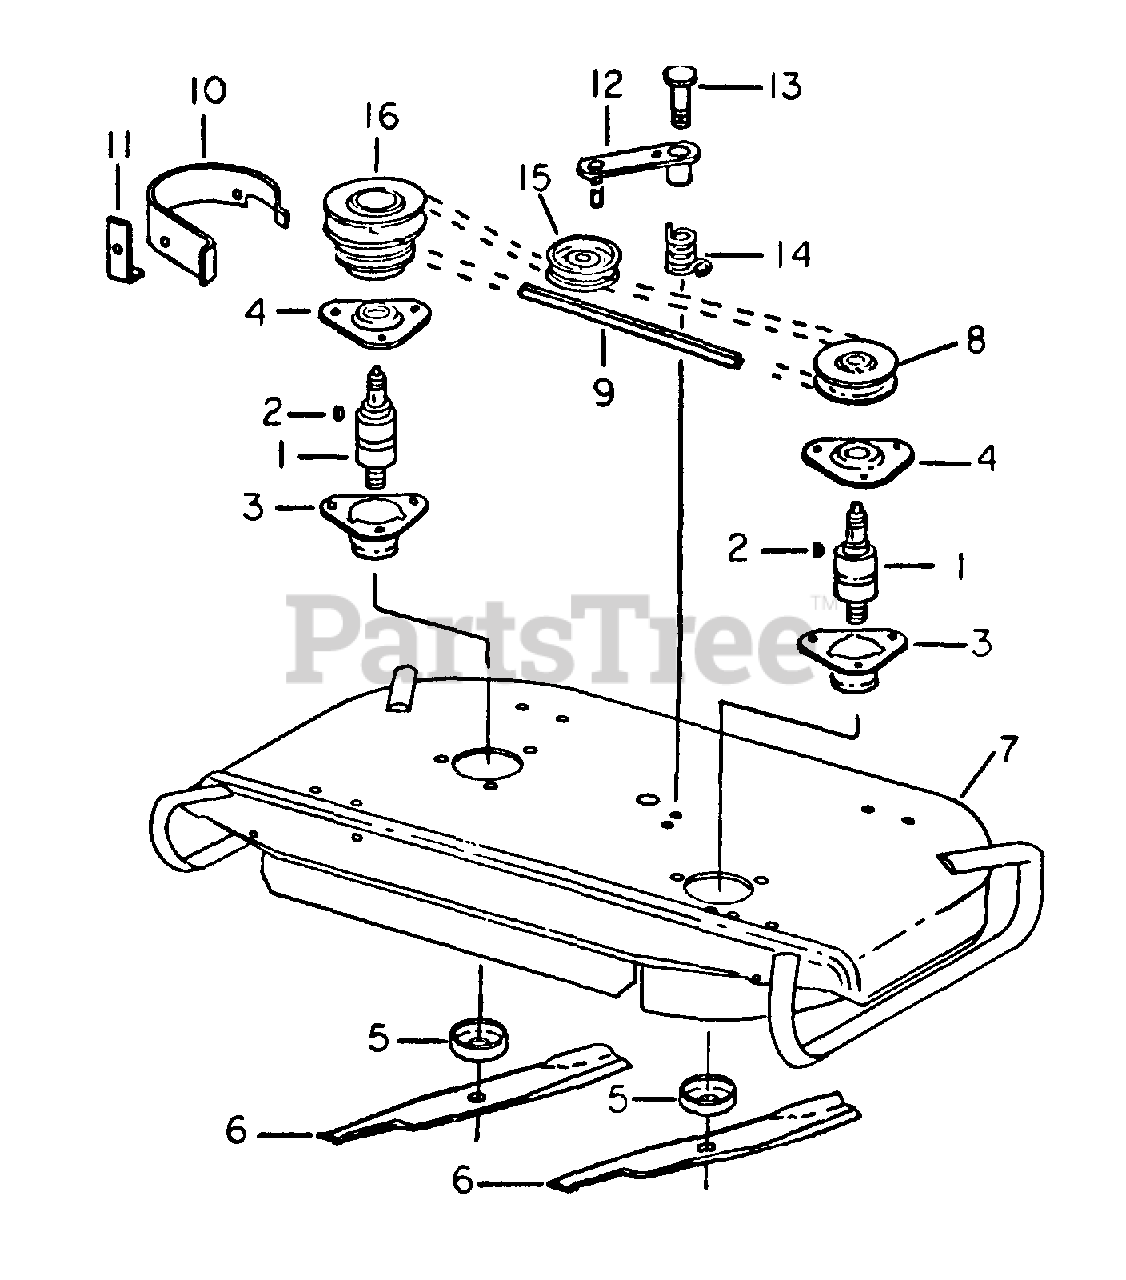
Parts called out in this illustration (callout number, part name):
1	BEARING, BALL AND FAN TYPE
2	KEY, 1/4 X 3/4 WOODRUFF 91
3	HOUSING, SPINDLE
4	CAP, SPINDLE HOUSING
5	CUP, SPINDLE
6	BLADE, 32 IN. -COATED EDGE-
6	BLADE, 32 IN.
7	HOUSING W/PRODUCT GRAPHIC. IH-57801-C2. 32 IN. MOWER
8	PULLEY, BLADE
9	BELT, BLADE DRIVE
10	SHIELD, BELT GUIDE
11	BRACKET, BELT GUIDE
12	ARM ASSY, IDLER
13	BOLT, IDLER ARM PIVOT
14	SPRING, TORSION
15	PULLEY, IDLER
16	PULLEY, LH SPINDLE
